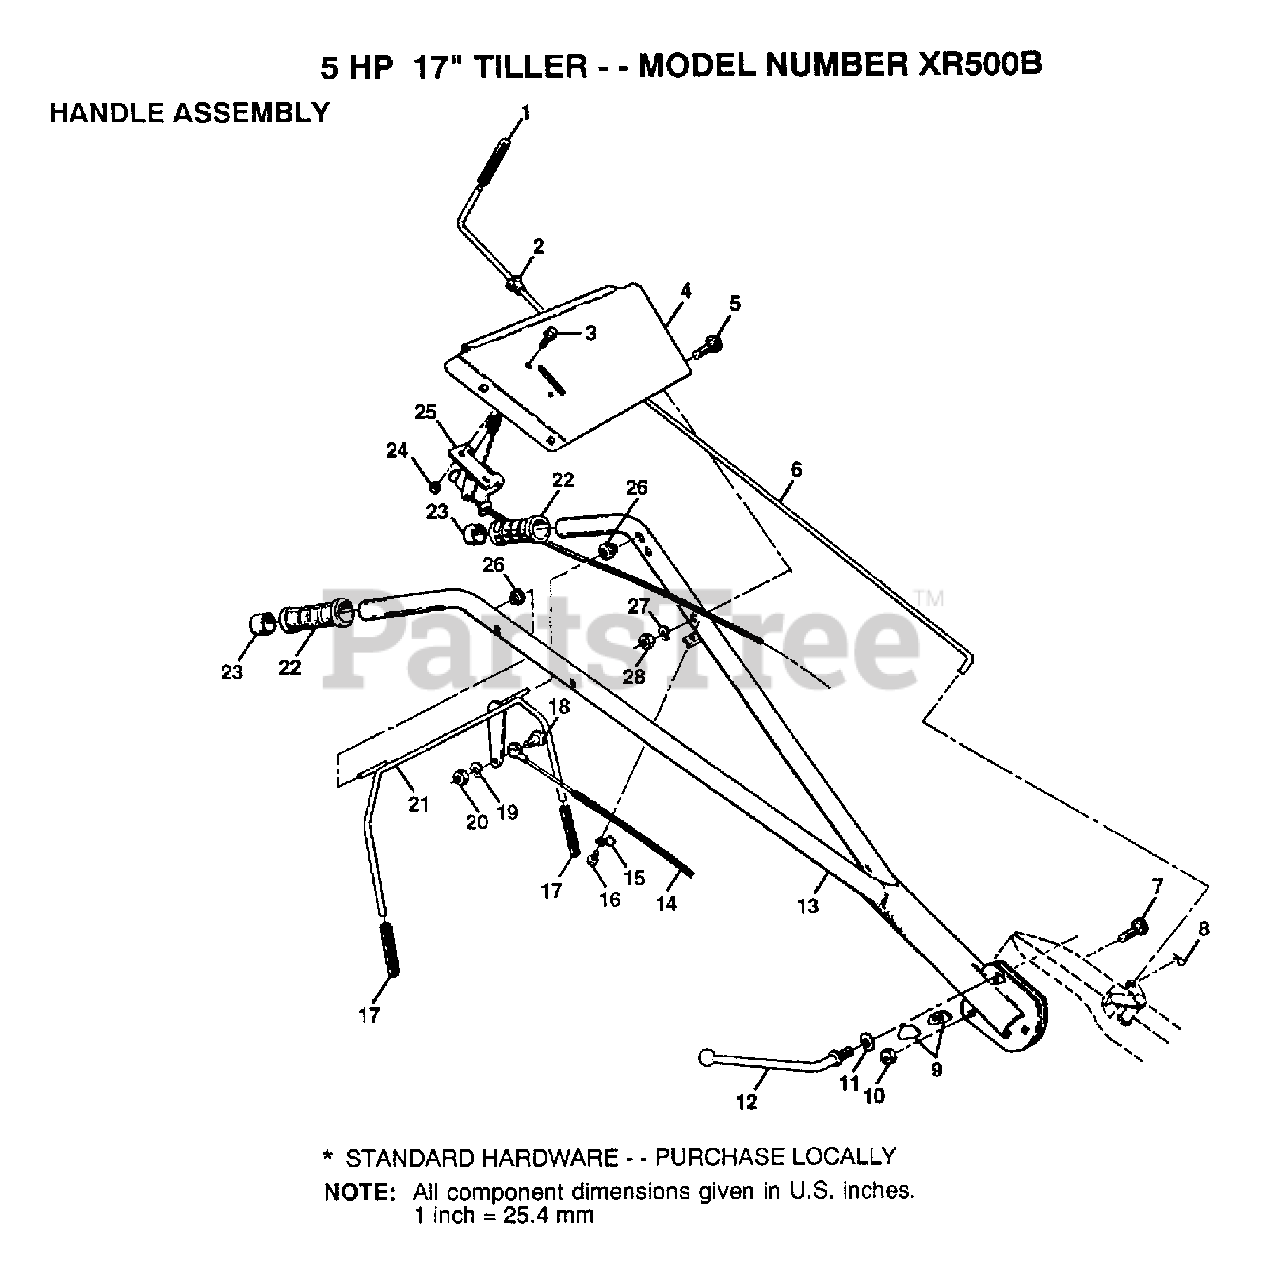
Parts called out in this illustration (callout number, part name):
1	GRIP TI
2	BUSHING
3	SCREW
4	"BRKT,HDLE TI"
5	BOLT CARRIAGE CRT
6	ROD SHIFT CRT
7	BOLT D
8	RETAINER M
9	LOCK CRT
10	LOCKNUT
11	WASHER CRT
12	LEVER LOCK CRT
14	CABLE.CLUTCH.CRT
15	CONDIUT CLIP T
17	GRIP BAR CRT
18	SHOULDER BOLT ST
19	LOCKWASHER
21	HANDLE BAR CRT
23	CAP CRT
25	"CONT,THROTTLE"
27	LOCKWASHER
